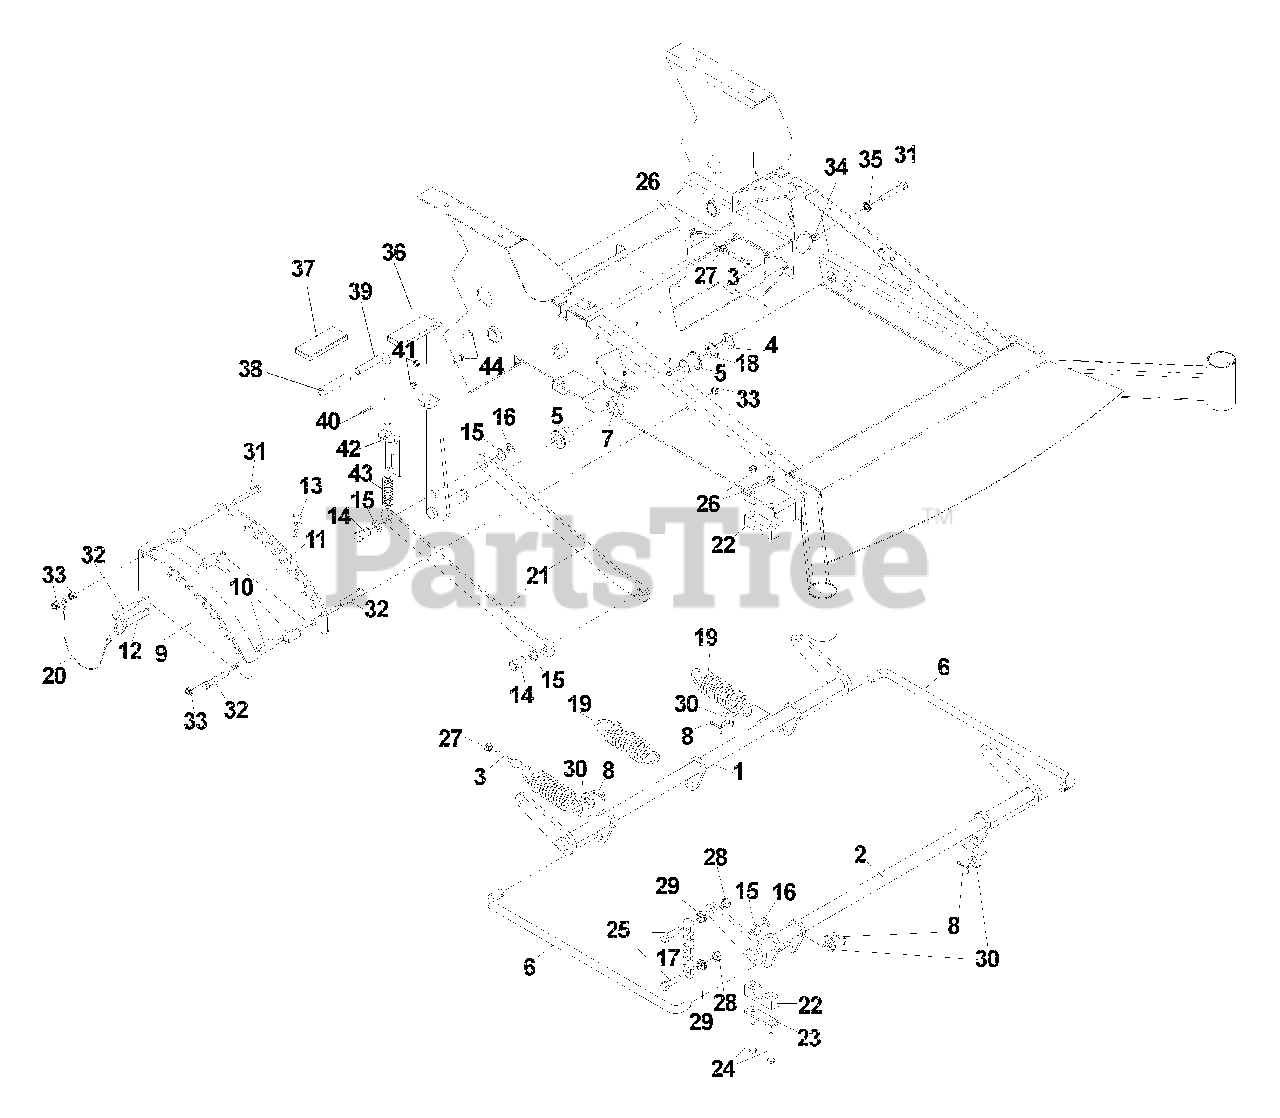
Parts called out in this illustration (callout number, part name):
1	Shaft, lift, rear
2	Shaft, lift, front
3	Eyebolt, right
4	E-ring, 7/8
5	Bushing, flanged-PM
6	Link, connecting
7	Zerk, long
8	Pin, cotter, 5/32 x 1 1/4
9	Adjustment plate
11	Adjustment plate
13	Hairpin, #4
14	Pin, clevis
15	Bushing, machine, 5/8
16	E-ring, 5/8
17	Lift chain
18	Bushing, machine, 7/8
19	Spring, extension
21	Lift linkage
22	Pillow block
23	Bar, reinforcement
24	Bolt, 5/16-18 x 2 1/2
25	Bolt, 7/16-14 x 1 1/2
26	Nut, 5/16-18, centerlock
27	Nut, 5/16-18, serrated washer
28	Nut, 7/16-14, centerlock
29	Nut, 7/16-14, whiz
30	Washer, 5/8
31	Bolt, 3/8-16 x 2 1/2
32	Bolt, 3/8-16 x 2 1/4
33	Nut, 3/8-16, centerlock
34	Nut, 3/8-16, nyloc
35	Nut, 3/8-16, serrated washer
40	Pin, 3/16 x 1 1/4, grooved
41	Nut, 1/4-20, centerlock
42	Pin mt, upper
44	Bolt, 1/4-20 x 3/4
